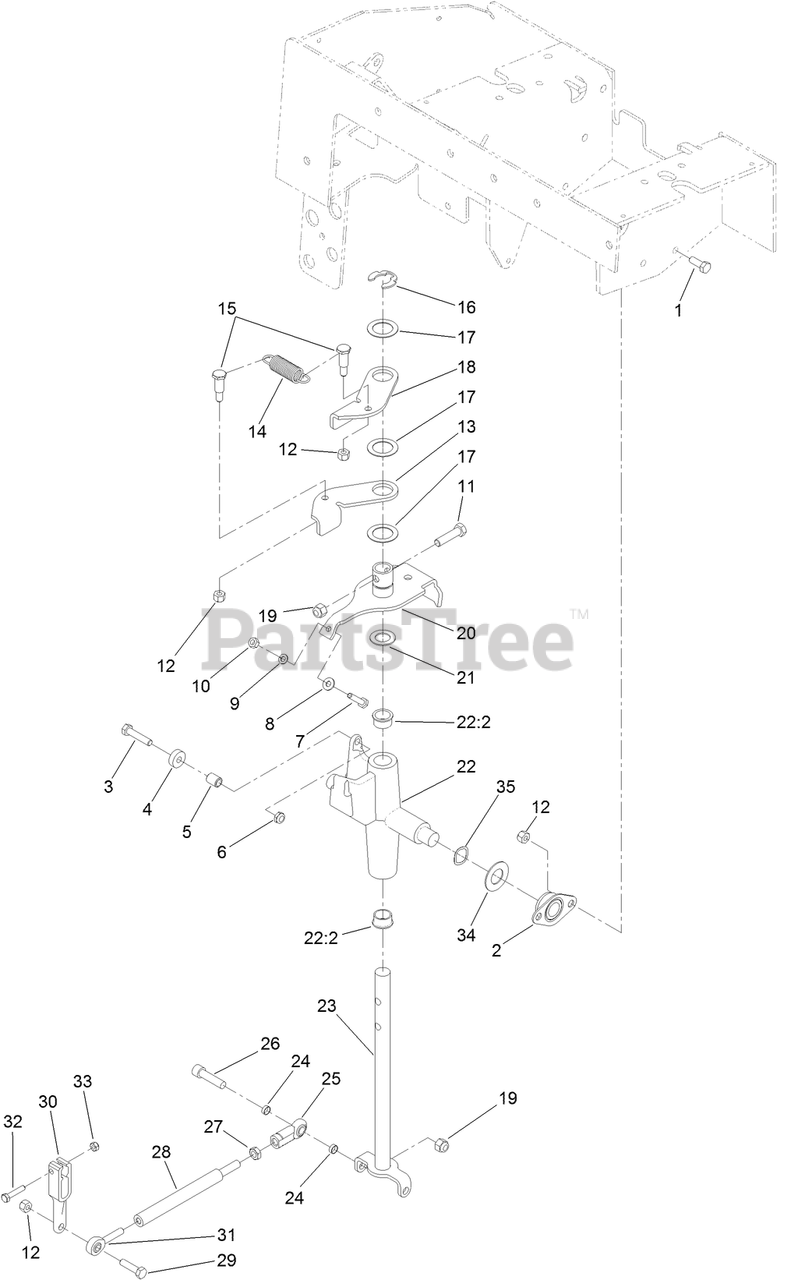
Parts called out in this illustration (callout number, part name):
1	SCREW-HH
2	BEARING
3	SCREW-HH
4	BEARING-BALL
5	SPACER-LEVER, CONTROL
6	NUT-LOCK, NI
7	SCREW-HH
8	WASHER-FLAT
9	SCREW-HH
10	NUT-HEX
11	SCREW-HH
12	NUT-LOCK, NI
13	LEVER-RETURN, RH
14	SPRING-EXTENSION
15	SCREW-SHOULDER
16	RING-RETAINING
17	WASHER-PLAIN
18	LEVER-RETURN, LH
19	NUT-LOCK, NI
20	LEVER-PIVOT
21	WASHER-THRUST
22	CONTROL SUPPORT ASM
22:2	BEARING-FLANGE
23	ROD-DRIVE
24	SPACER
25	JOINT-BALL END, LH
26	SCREW-HSH
27	NUT-HEX JAM, LH
28	ROD-LINKAGE
29	SCREW-HH
30	ARM-CONTROL, PUMP
31	BEARING-ROD END, RH
32	SCREW-HH
33	NUT-LOCK
34	WASHER-FLAT
35	WASHER-SPRING, WAVE
